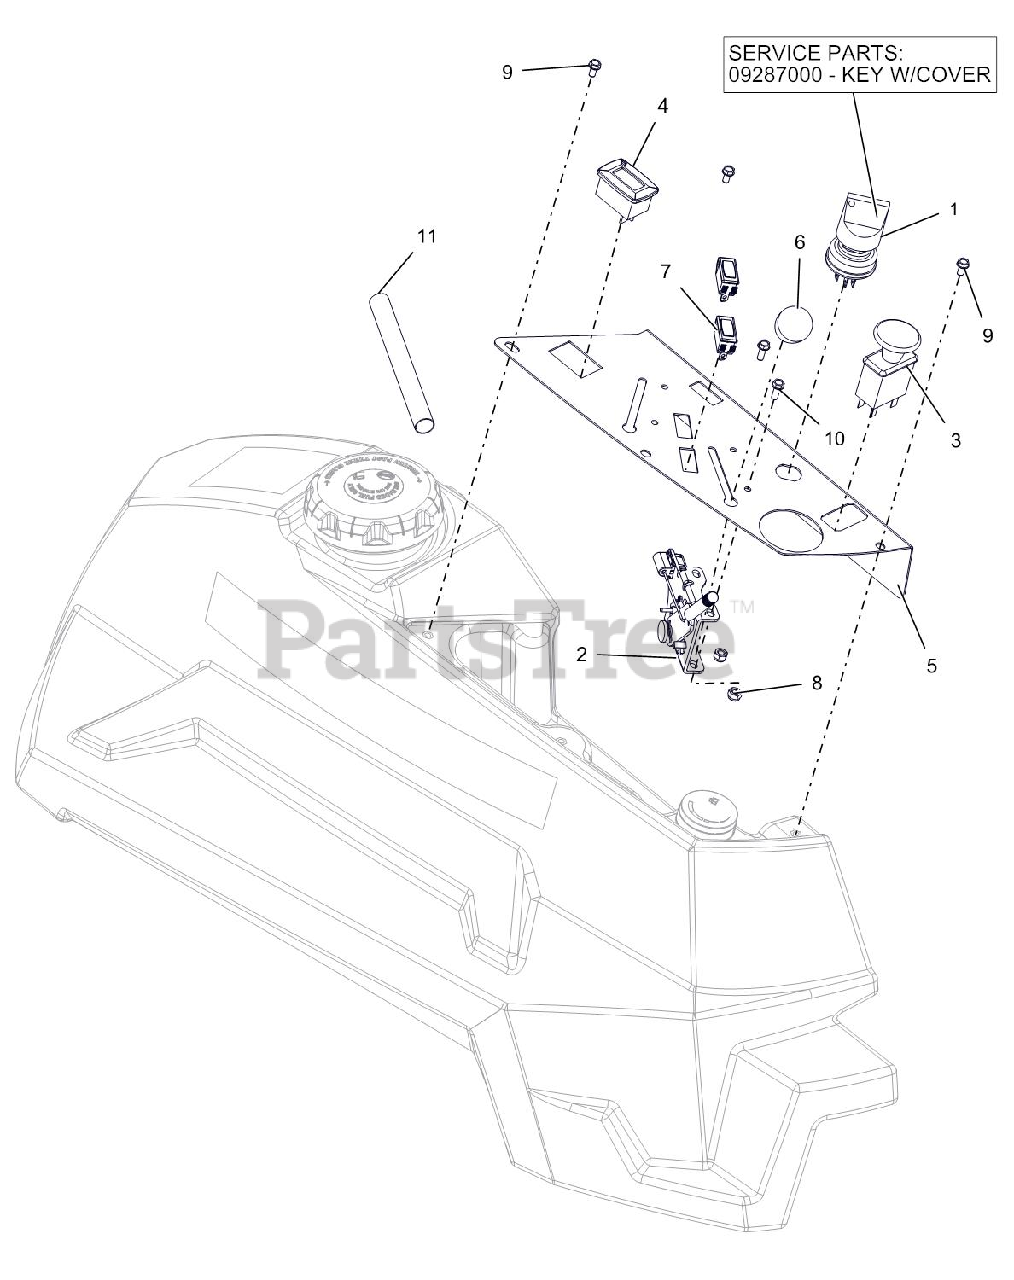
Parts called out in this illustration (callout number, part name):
1	KEY, W/ SHIELD
1	SWITCH, IGNITION
2	CABLE, PRO-CTRL 43.00"
3	SWITCH, CLUTCH
4	METER, HOUR W/MAINTENANCE
5	PT400 CONTROL PANEL - RED
6	KNOB-CONTROL-BLACK .38-16X.50
7	LIGHT,INDICATOR
8	@NUT-LK-NYL 10-24 W/INSRT YWZC
9	SCR-MCH 10-24X.38 HWHSTAINLESS
10	@SCR-MCH 10-24X.50 HWH YWZC
11	SLEEVE, THERMAL 6"
